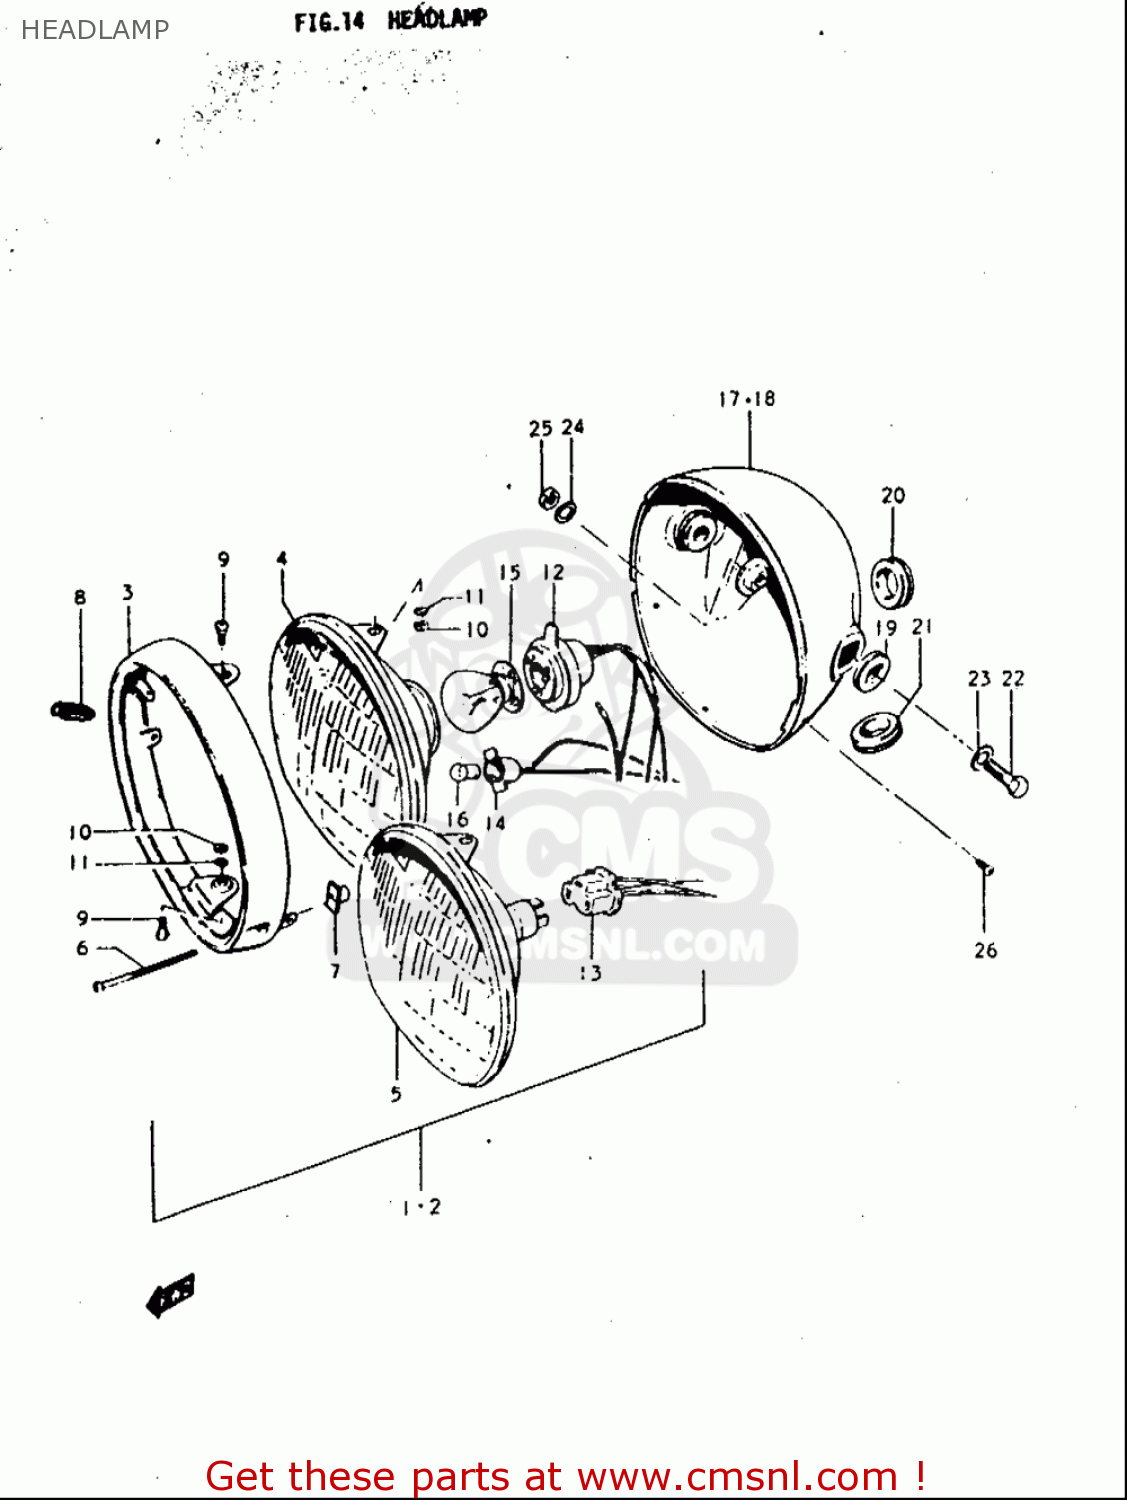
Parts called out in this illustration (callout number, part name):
7	NUT
8	SPRING,HEADLAMP ADJUST
9	H/LAMP LENS UNIT FITING SCRE
10	NUT
11	WASHER,LOCK
14	SOCKET
16	BULB(12V3.4W,STANLEY,A72A)
22	BOLT
23	WASHER
24	WASHER,LOCK
25	NUT
